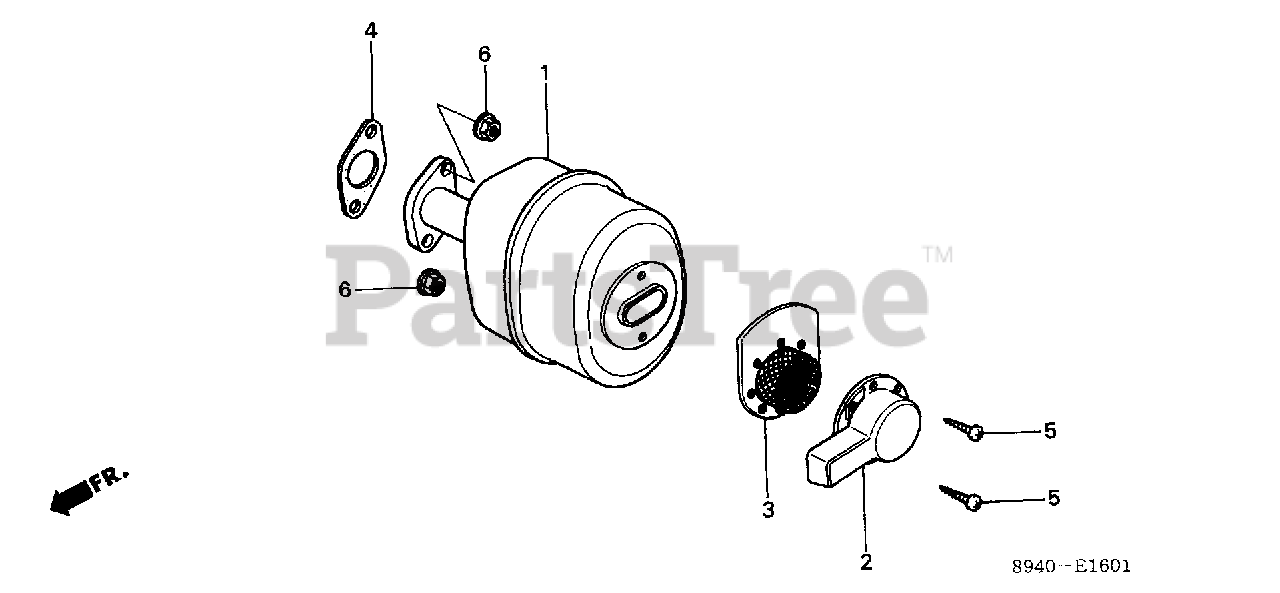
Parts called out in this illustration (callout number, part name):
1	MUFFLER ASSY.
2	CAP, MUFFLER (NOT AVAILABLE)
3	ARRESTER, SPARK
4	GASKET, MUFFLER
5	SCREW, TAPPING (4X8)
6	NUT, FLANGE (8MM)
